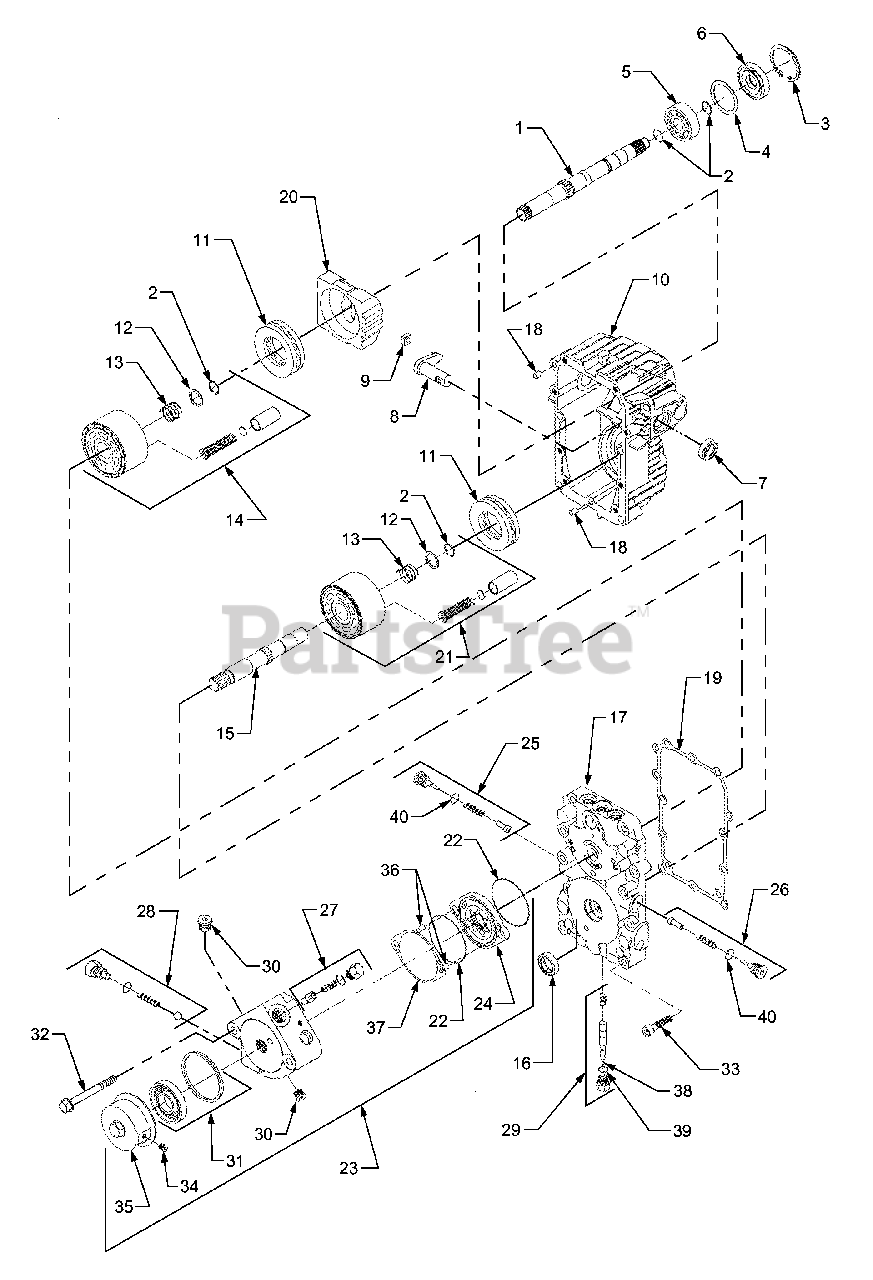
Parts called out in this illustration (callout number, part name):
1	Shaft, Pump
2	Ring, Wire Retaining
3	Ring, Retaining
5	Bearing, Ball
6	Seal, Lip
8	Arm, Trunnion
9	Guide, Slot
10	Housing Assembly
11	Bearing Assembly, Thrust Ball
12	Washer, Block Thrust
13	Spring, Block
14	Kit, Pump Cylinder Block
15	Shaft, Motor
16	Not Used In This Application
17	Kit, Center Section
19	Gasket, Center Section
20	Swashplate, Variable
21	Kit, Motor Cylinder Block
23	Kit, Auxiliary Charge Pump
24	Gerotor & Housing Assembly
25	Kit, Check Valve
26	Kit, Check Valve w/ .044 Orifice
27	Kit, Check Relief
28	Kit, Auxiliary Relief Valve
29	Kit, Bypass Valve
31	Kit, Auxliary Filter
32	Screw, Flange Head Cap, M8 x 60
33	Screw, Socket Head Cap
35	Cover, Filter
37	Shim, Charge Pump
38	O-Ring-Order Seal Kit HG-2510010
39	O-Ring-Order Seal Kit HG-2510010
40	O-Ring-Order Seal Kit HG-2510010
